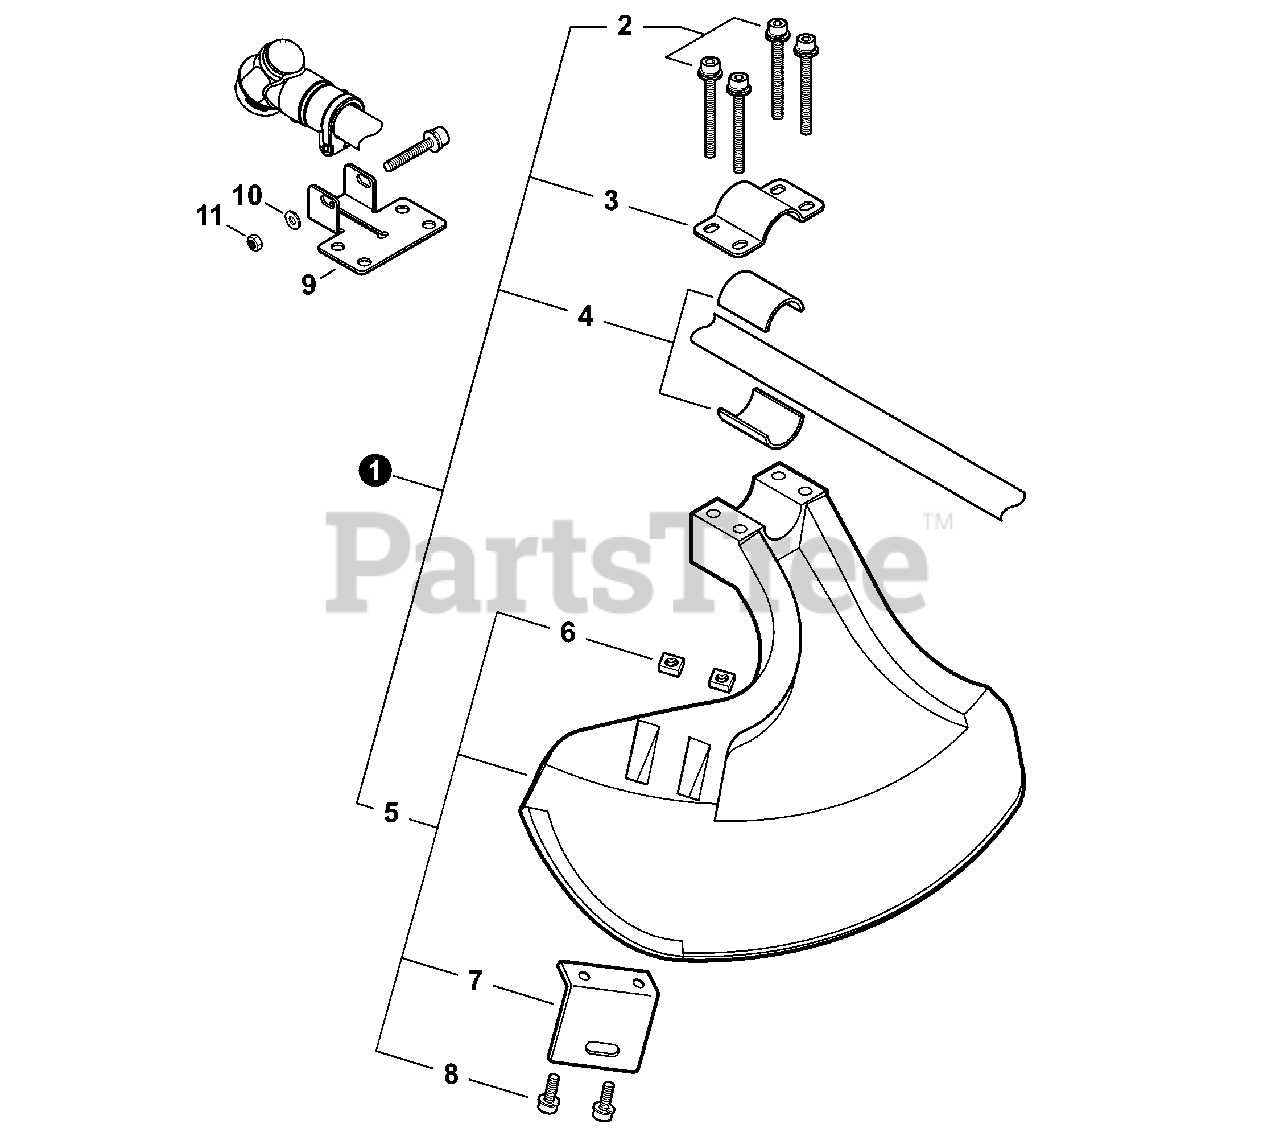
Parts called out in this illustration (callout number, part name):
1	DEBRIS SHIELD KIT
2	BOLT M5×45
3	CLAMP, UPPER
4	SPACER 24
5	DEBRIS SHIELD ASSY
8	BOLT M5×16
9	PLATE, SHIELD MOUNTING
10	WASHER 5.5×12×0.8
11	NUT M5
